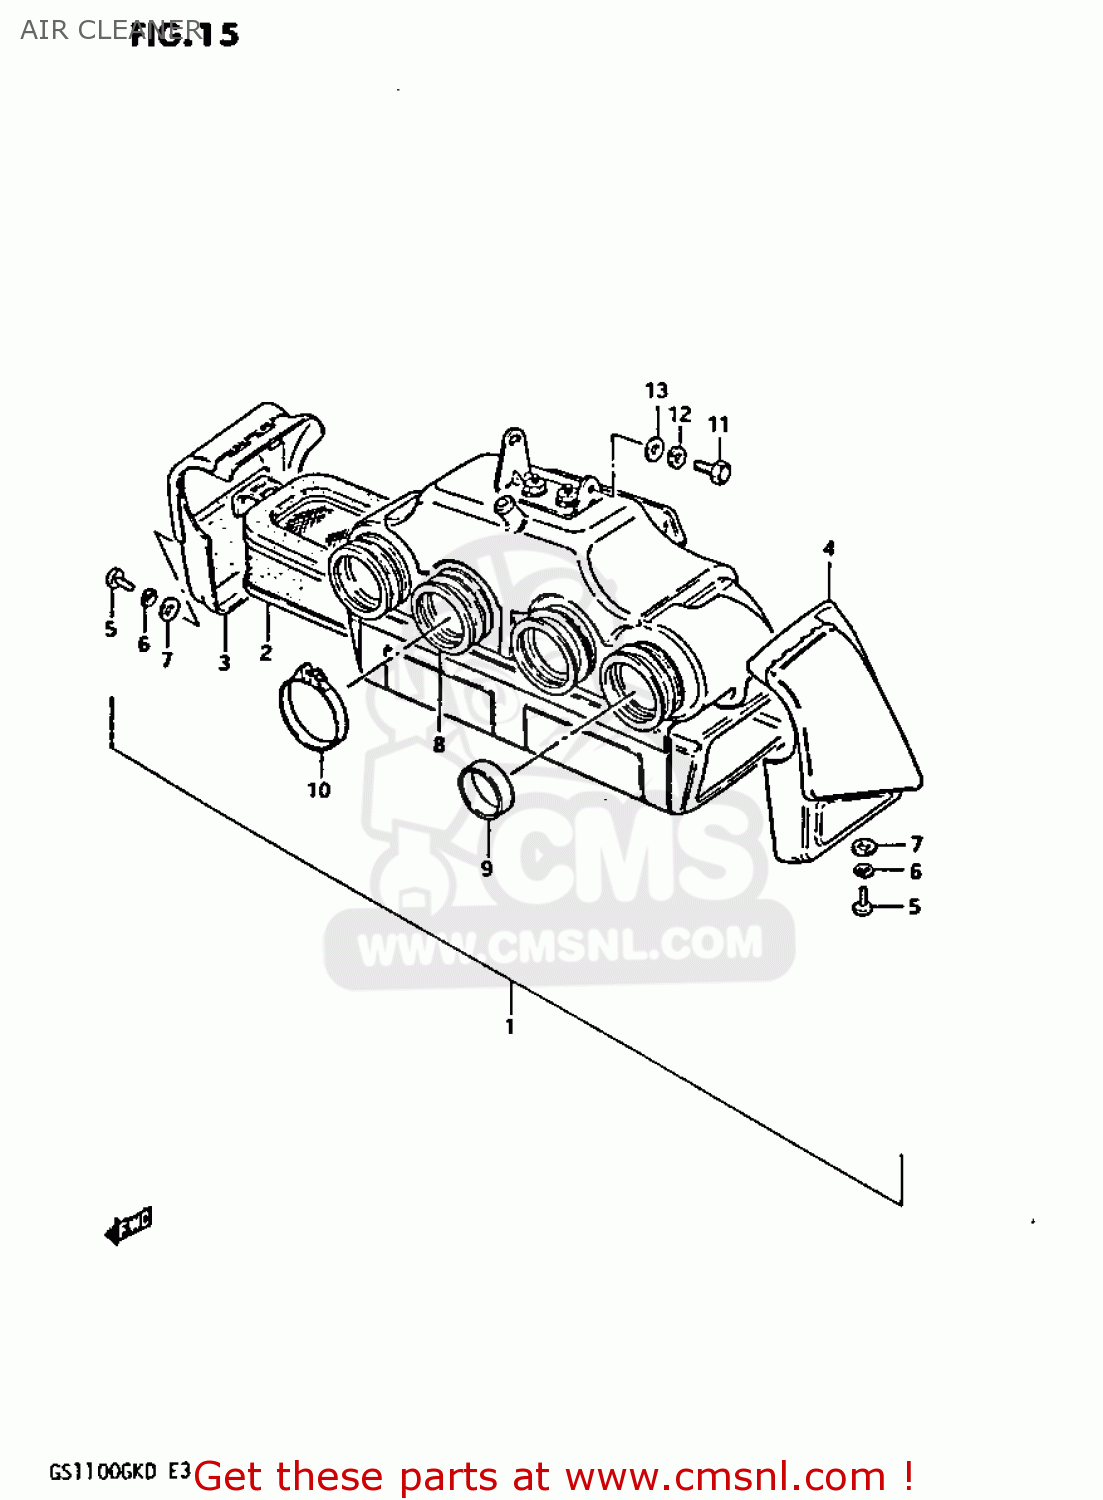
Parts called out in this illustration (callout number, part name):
1	CLEANER ASSEMBLY,AIR
2	FILTER ASSY
3	CAP,AIR CLEANER
4	CAP,AIR CLEANER
5	SCREW
6	LOCK WASHER
7	WASHER
8	TUBE,OUTLET
9	RING,CARBURETOR AIR IN
10	CLAMP
11	BOLT
12	WASHER,LOCK
13	WASHER 6MM
